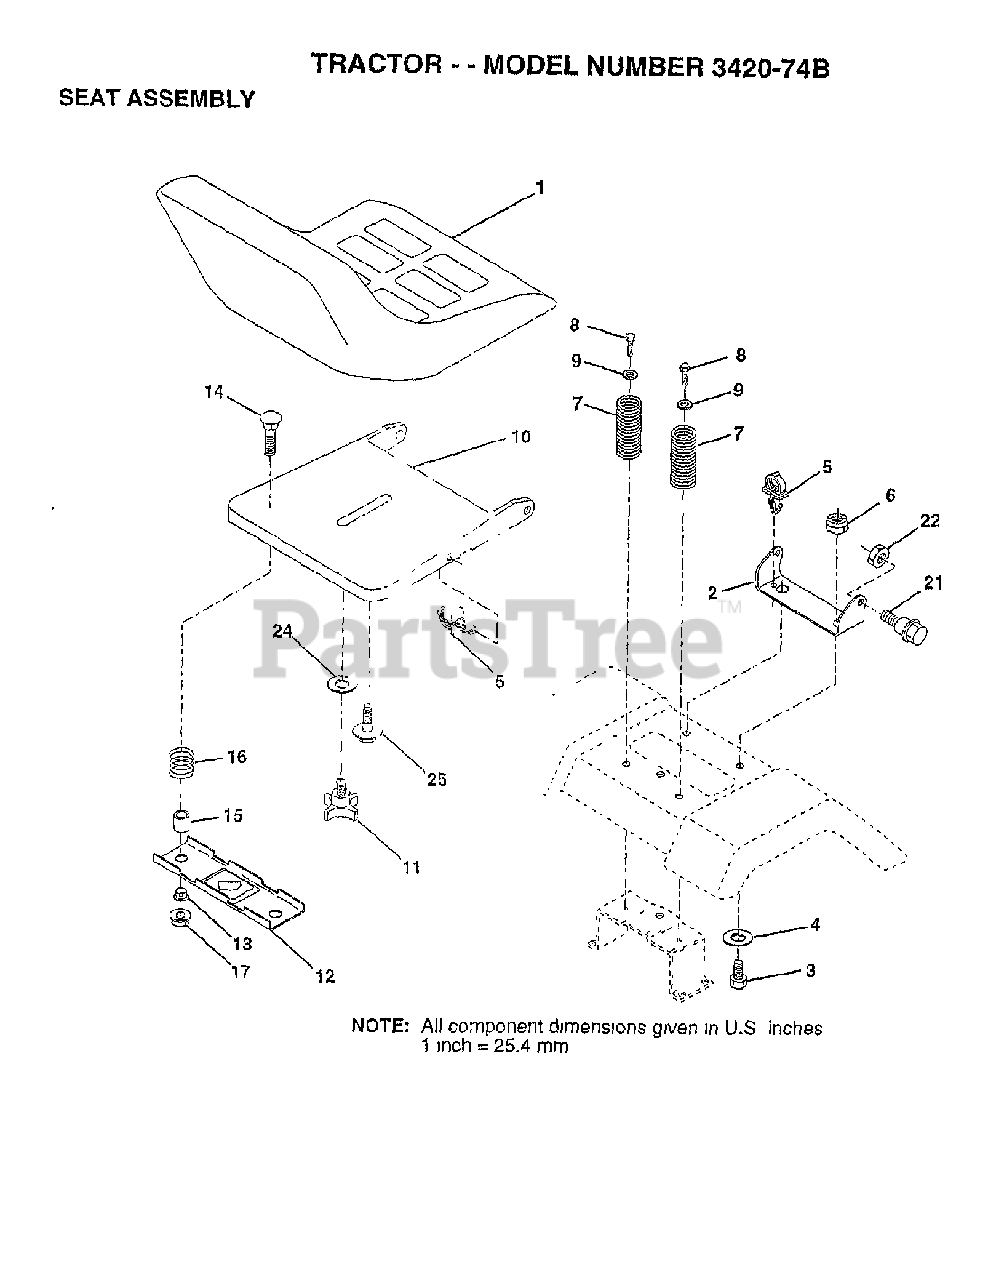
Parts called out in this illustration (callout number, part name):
2	BRKT,SEAT PIVOT**
3	BOLT
4	WASHER PM
5	PUSH CLIP
6	NUT
7	SPRING COMPRESSION
8	SCREW GTV
12	BRKT SWITCH
14	BOLT CARRIAGE 1/4-20X1 3/8
15	SPACER SPLIT
16	SPRING COMPRESSED
17	NUT T
22	LOCKNUT
25	BOLT, SHOULDER**
